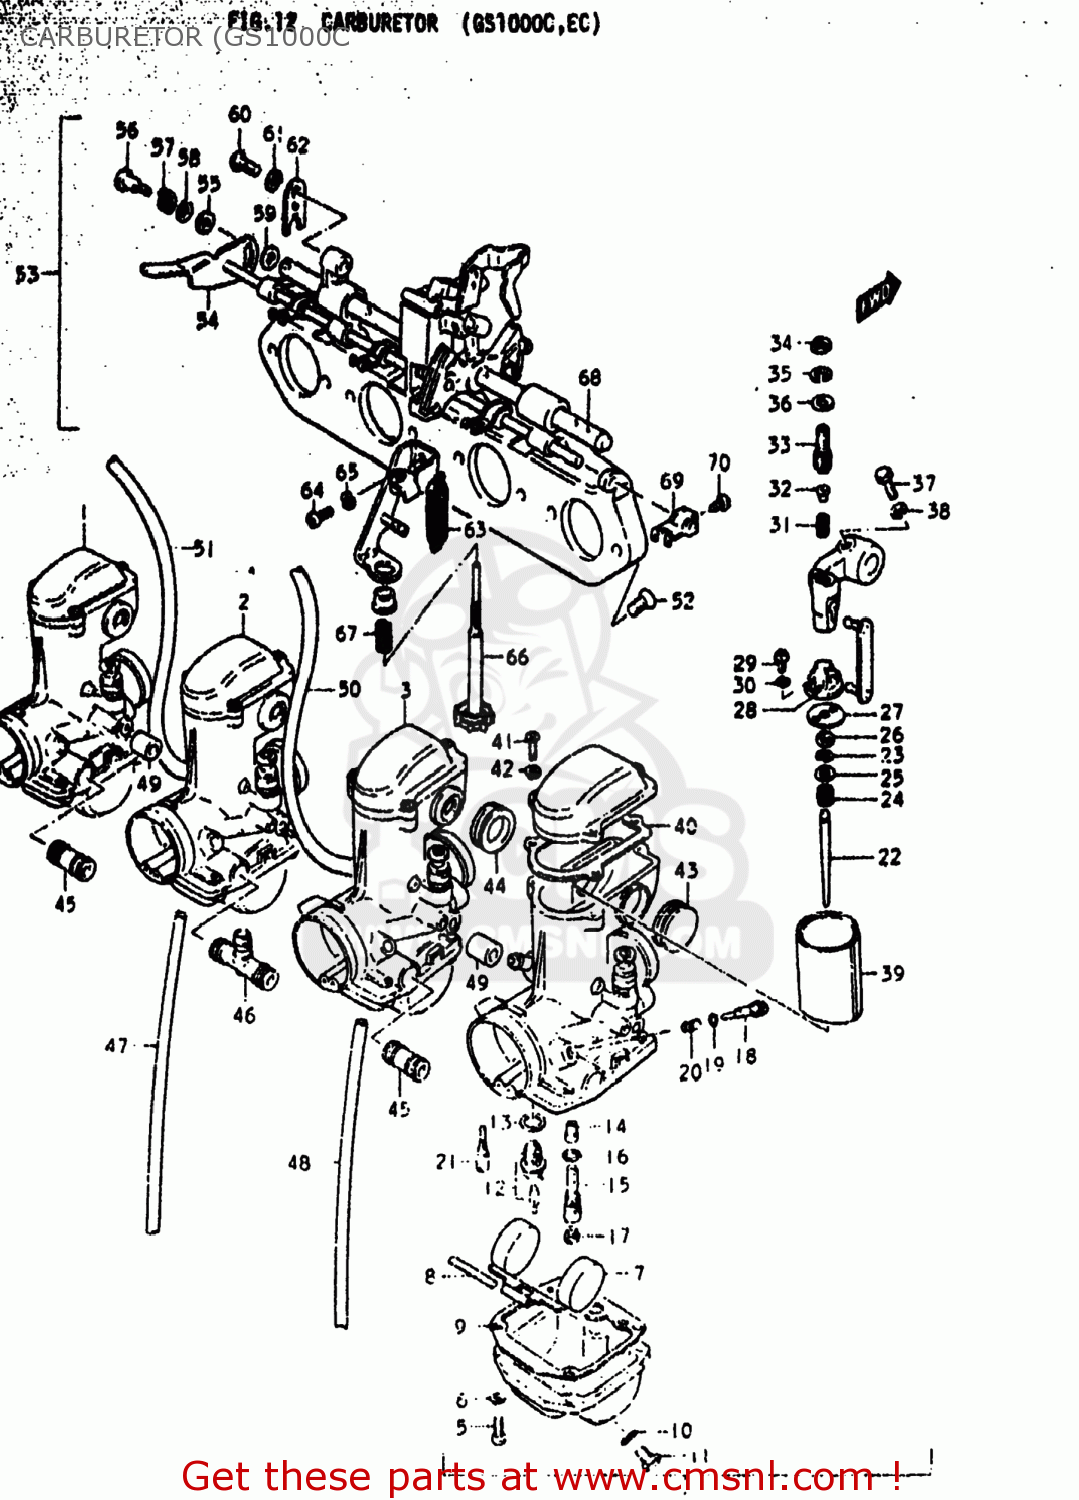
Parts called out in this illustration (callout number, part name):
1	CARBURETOR ASSEMBLY
2	CARBURETOR ASSEMBLY
3	CARBURETOR ASSEMBLY
4	CARBURETOR ASSEMBLY
5	SCREW
6	LOCK WASHER
7	FLOAT
8	PIN,FLOAT
9	GASKET,FLOAT CHAMBER (NAS)
10	O RING
11	SCREW
12	VALVE ASSEMBLY,NEEDLE
13	GASKET,VALVE SEAT (NAS)
14	JET,NEEDLE
15	PIPE,BLEEDER
16	O RING
17	JET,MAIN(95)
18	SCREW,PILOT AIR
19	O RING
20	SPRING
21	JET,PILOT
22	NEEDLE,JET
23	CLIP
24	SPRING
25	WASHER,JET NEEDLE
26	RING
27	PLATE,THROTTLE VALVE
28	CONNECTOR
29	SCREW
30	WASHER,LOCK
31	SPRING
32	PIN,CARBURETOR
33	SCREW
34	NUT
35	LOCK WASHER
36	WASHER
37	BOLT
38	LOCK WASHER
39	VALVE,THROTTLE
40	GASKET (NAS)
41	SCREW
42	LOCK WASHER
43	PIPE,DELIVERY
44	SEAL
45	NIPPLE
46	NIPPLE
47	HOSE
48	HOSE
49	HOSE
50	HOSE
51	HOSE 4.5X8X390
52	SCREW
53	CARBURETOR ASSEMBLY
54	SHAFT,STARTER
55	WASHER
56	SCREW,STARTER LEVER
57	SPRING
58	WASHER,STARTER SHAFT
59	WASHER,STARTER SHAFT
60	SCREW
61	LOCK WASHER
62	GASKET
63	SPRING
64	SCREW
65	LOCK WASHER
66	ADJUSTER
67	SPRING,THROTTLE SCREW
68	SHAFT ASSEMBLY
69	LEVER, STARTER
70	SCREW
